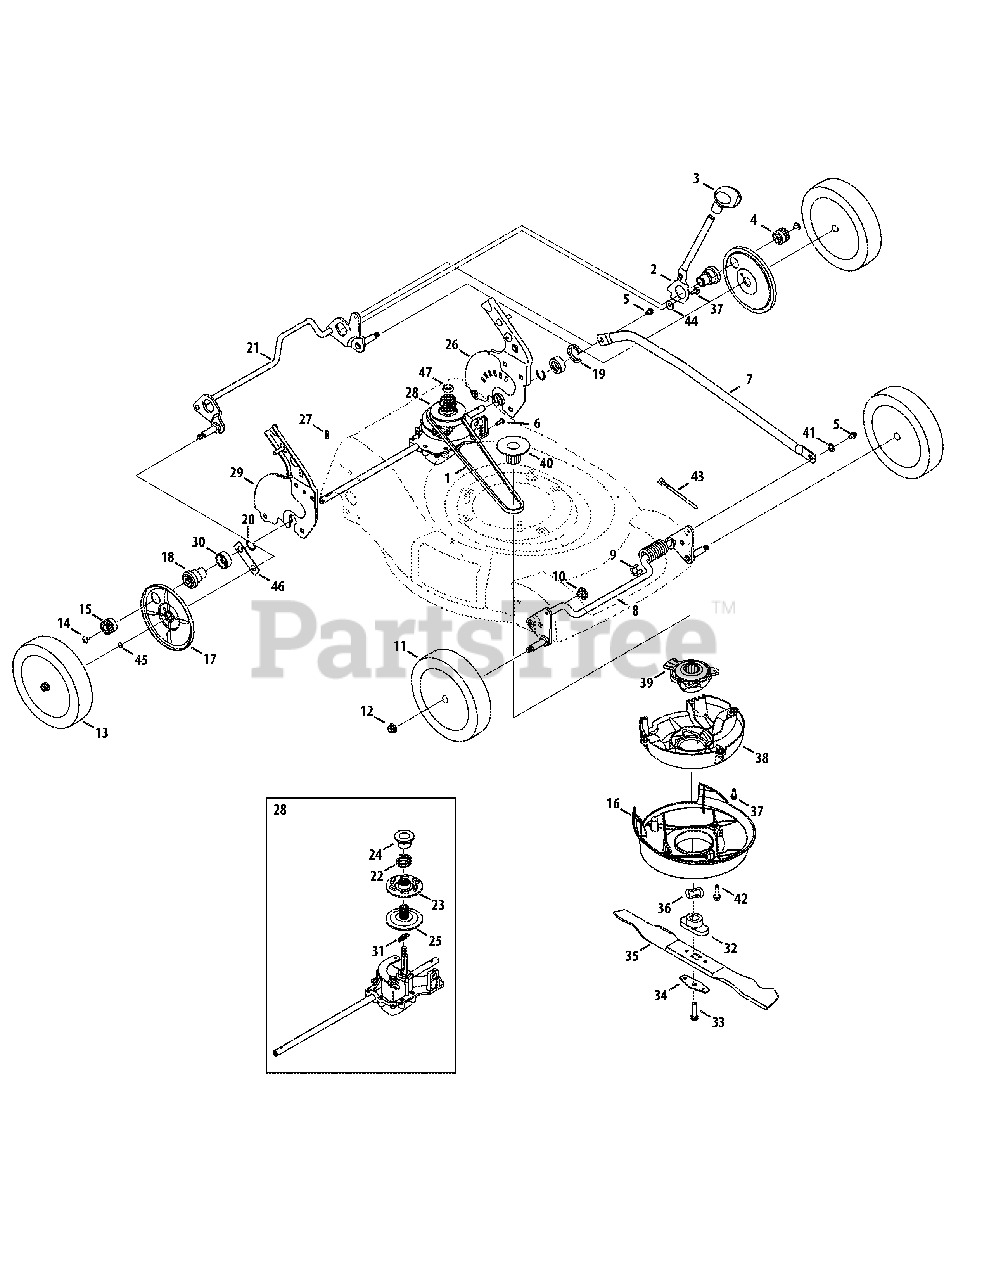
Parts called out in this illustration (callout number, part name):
1	V-Belt
2	Spring Lever
4	Spur Gear, 14T - LH
5	Shldr. Screw, 1/4-20 x 0.50
6	Screw, #12-16
9	Clip Spacer
10	Split Hex Flange Bearing
11	Front Wheel
12	Flange Lock Nut, 3/8-16
13	Rear Wheel
14	Screw, 1/4-20 x .39
15	Spur Gear, 14T - RH
17	Wheel Dust Cover
18	Transmission Bearing Support
19	Clip Spacer
20	Retaining Ring .875
22	Compression Spring
23	Upper Pulley
24	Nut, Shldr.
25	Lower Pulley
27	Dowel Pin
28	Transmission Assembly
30	Bearing Support Spacer
31	Extension Spring
32	Blade Adapter
33	Screw, 3/8-24 x 1.50
34	Blade Bell Support
35	21” Mulching Blade
36	Washer, Wave, .88 x 1.31 x .029
37	TT Screw, 1/4-20 x .500
38	BaffleEngine
39	Lower Pulley Assembly
40	Pulley, Half
41	Washer, Wave, .390 x .625 x .016
42	Screw, 1/4-15 x 1.250
43	Cable Tie
44	Washer, Bell, .340 x .872 x .080
45	Ring, .375ID x .054
46	Gear Retainer Strap
47	Spcr., 7/8 x 1.265
